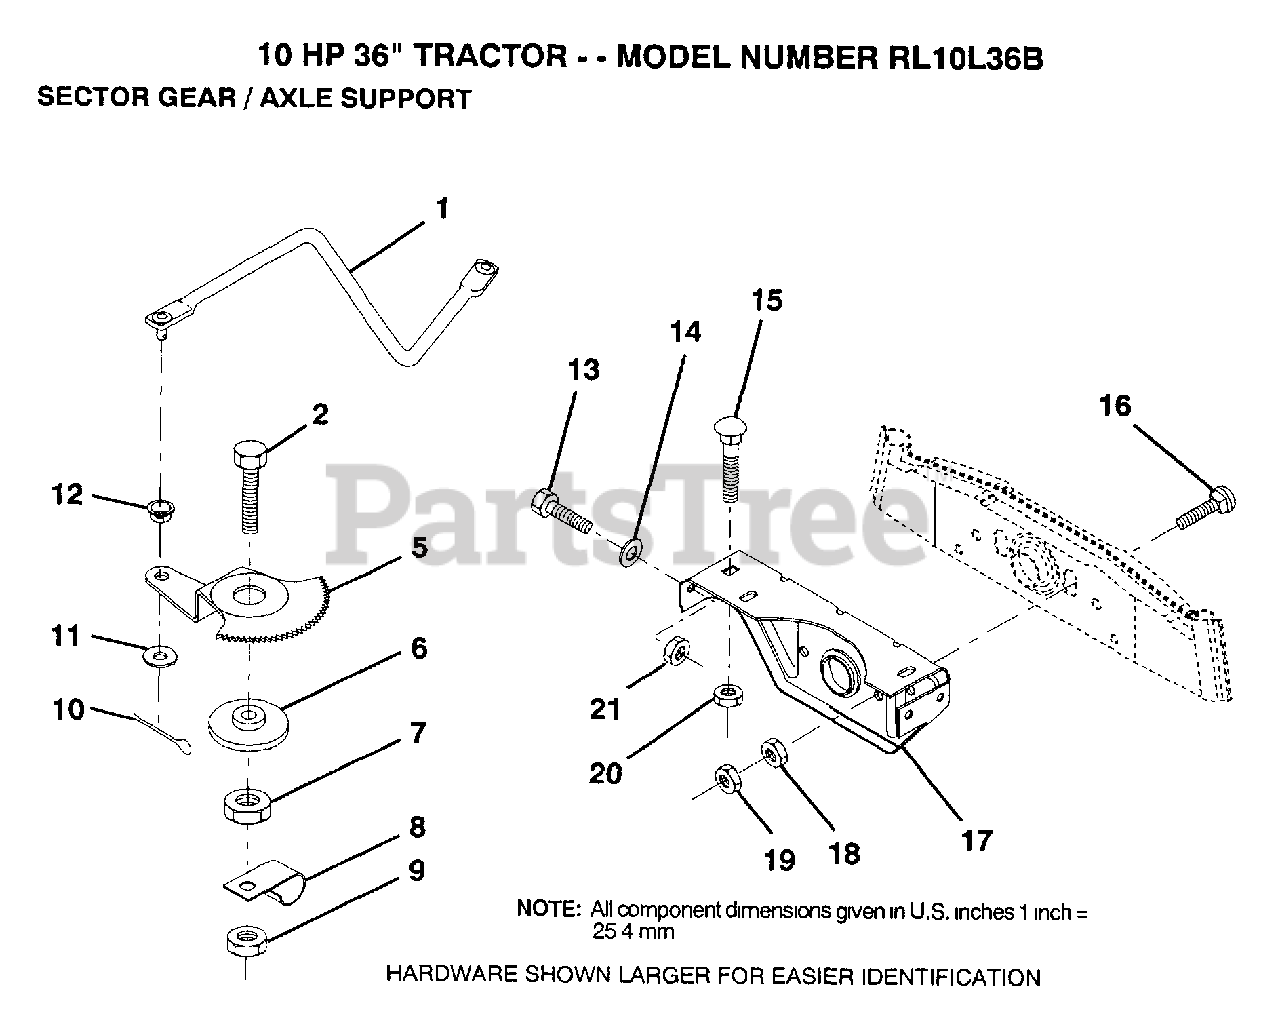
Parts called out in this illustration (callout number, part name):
1	DRAG LINK
2	"BOLT,HEX"
5	GEAR SECTOR
6	BUSHING
7	NUT
8	CLIP INSULATOR
9	NUT LTV
10	COTTER PIN
11	WASHER
12	BUSHING.DRAGLINK
13	BOLT
14	WASHER
15	BOLT
16	BOLT
17	"SUPT,FRT AXLE"
18	NUT.HEX.3/8-16UNC
19	LOCKNUT
